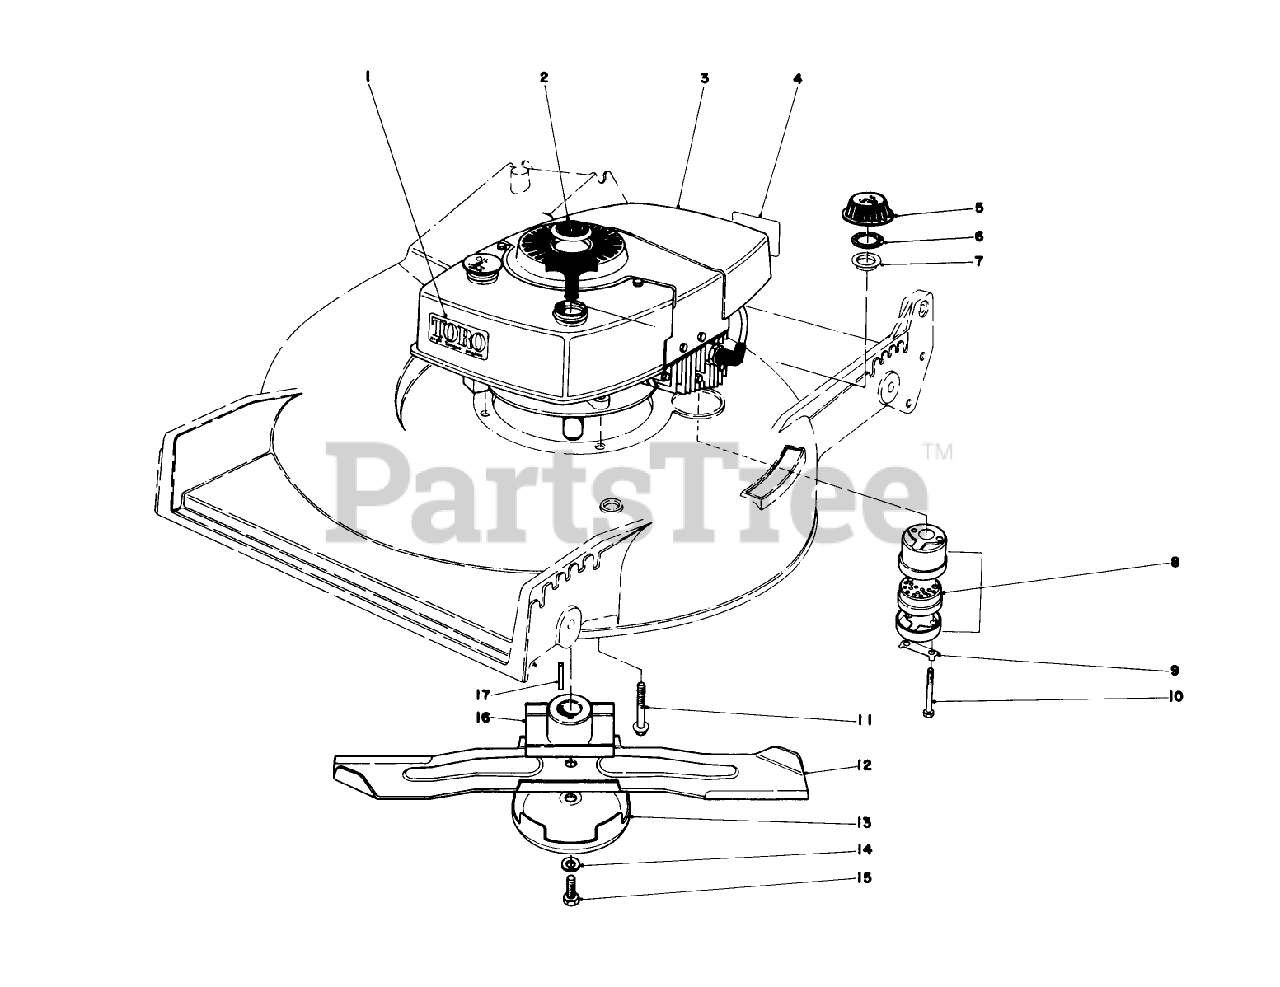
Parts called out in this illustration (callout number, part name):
1	High Torque
2	PLUG BUTTON
3	Engine
4	Decal-Maintenan
5	Gas Cap (Incl. Ref. #6 & 7)
6	Gasket-Gas Cap
7	GAS CAP BAFFLE
8	Muffler Assembly (Incl. Ref. #9 & 10)
9	CLIP - LOCKING
10	SCREW-HH
11	SCREW-HWHTF
12	Blade
13	AntiScalp Cup
14	WASHER-LOCK
15	BLADE SCREW
16	Retainer Blade
17	KEY-SQUARE
